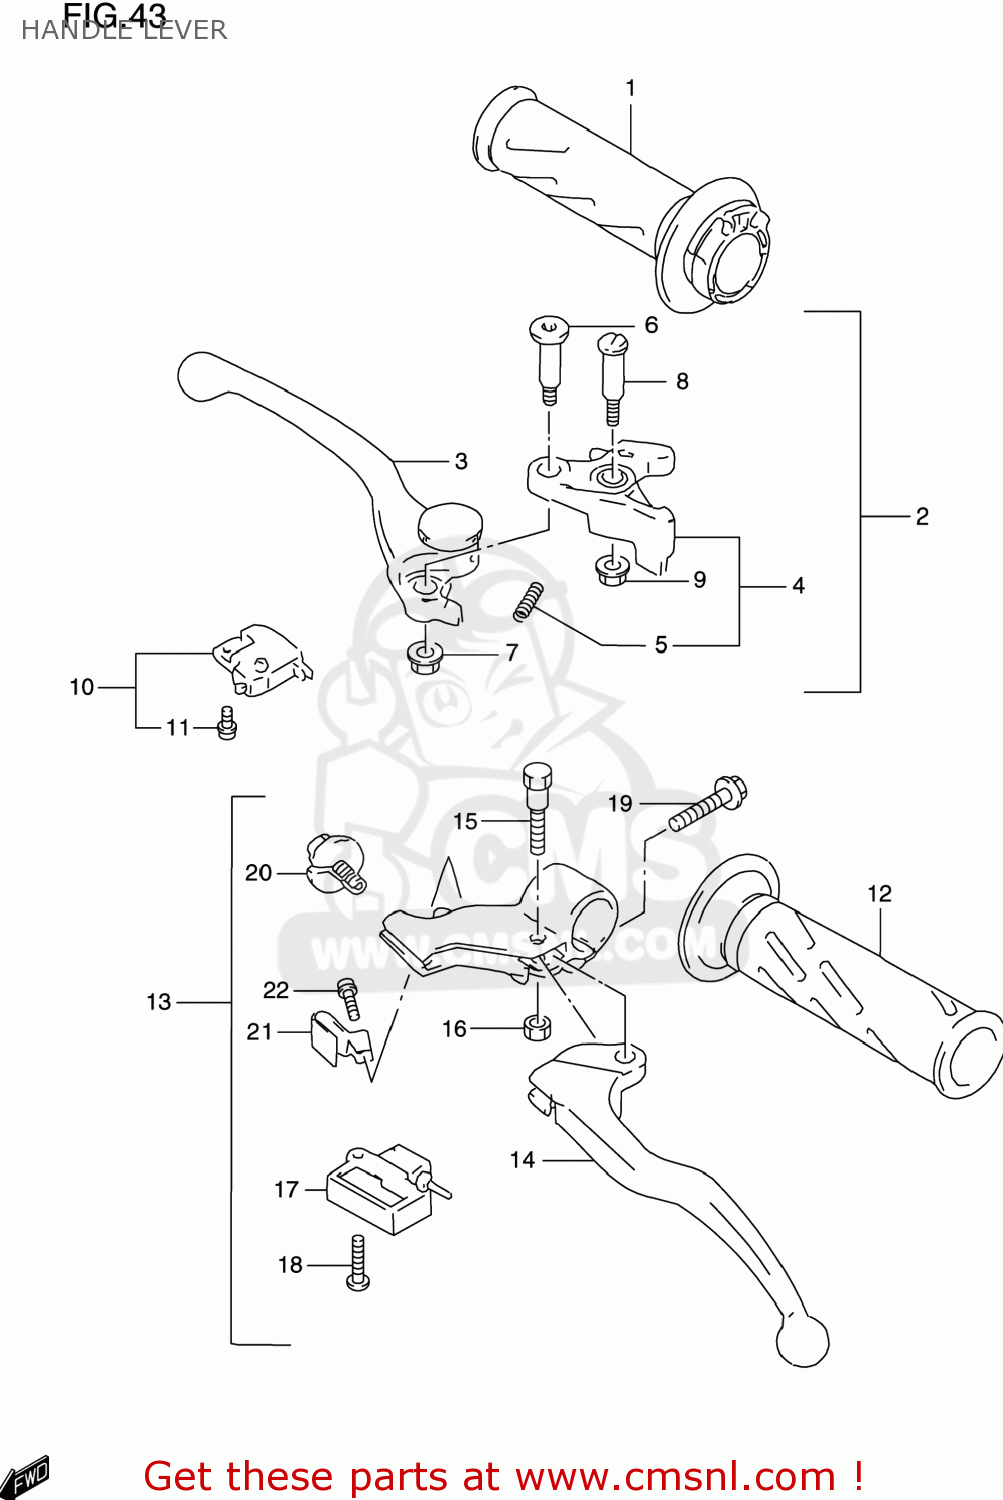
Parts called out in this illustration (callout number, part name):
1	GRIP,THROTTLE
2	LEVER ASSY,BRAKE
3	LEVER,ADJUST
4	KNOCKER
5	SPRING
6	BOLT,LEVER
7	NUT
8	BOLT,LEVER PIVOT
9	NUT
10	SWITCH ASSEMBLY,STOP
11	SCREW
12	GRIP,LEFT
13	LEVER ASSEMBLY,CLUTCH
14	LEVER,CLUTCH
15	BOLT,LEVER SET
16	NUT
17	SWITCH,CLUTCH
18	SCREW
19	SCREW
20	NUT,CABLE ADJUSTER
21	SPRING,ADJUST
22	SCREW,SPRING
